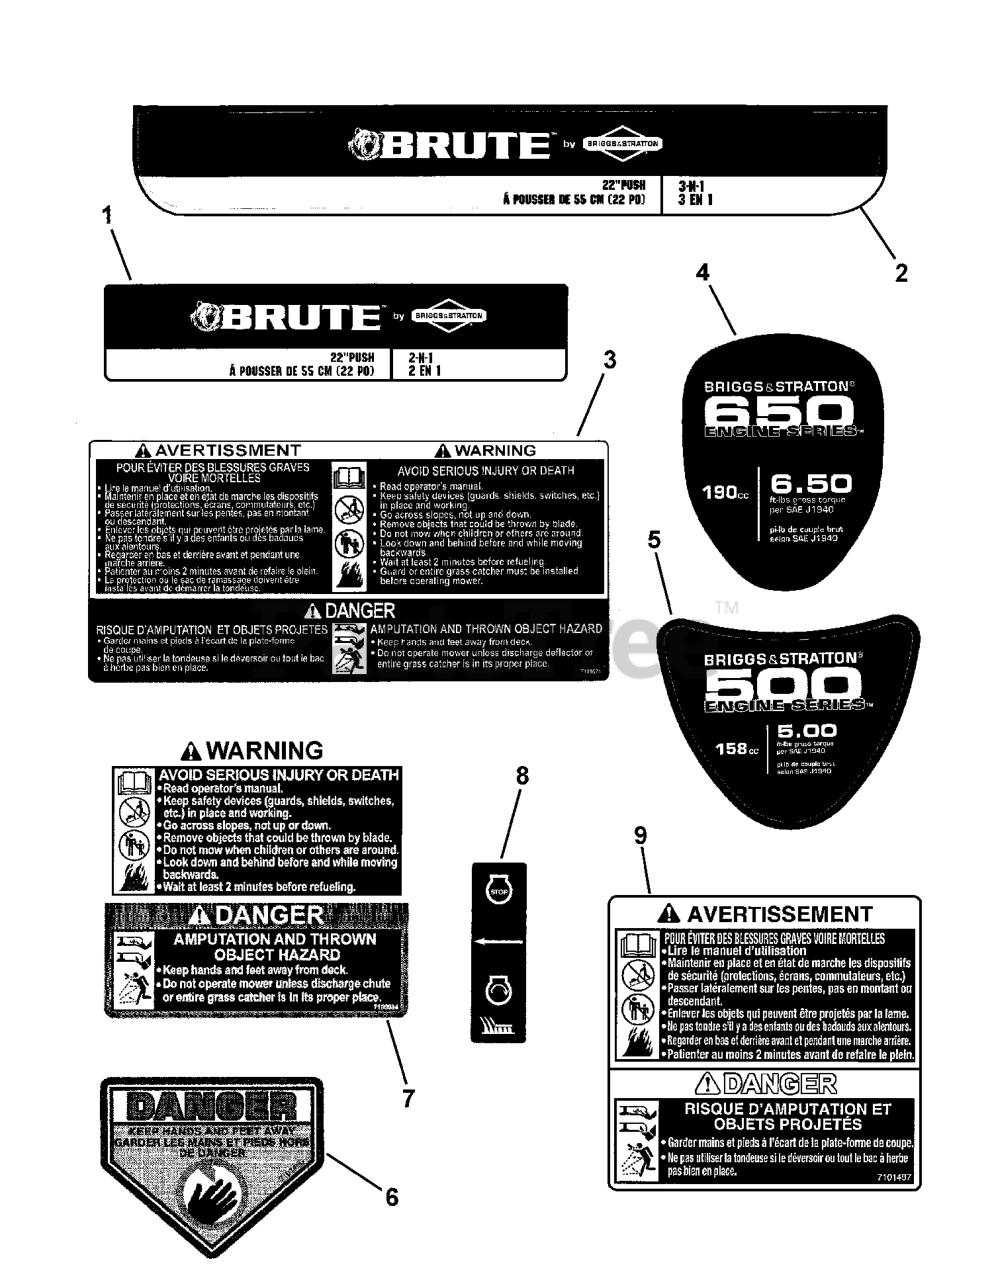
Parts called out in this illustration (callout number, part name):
1	DECAL, Brute Logo, Deck, FC
2	DECAL, Deck Front Brute 22" FC
3	DECAL, French/English, Walk-Behind Safety
4	DECAL, Engine, TP, Brute 650 FC
5	DECAL, Engine, Brute, TP, 500, FC
6	DECAL, CPSC, French/English
7	DECAL, Warning/Danger Walk-Behind Mower
8	DECAL, OPC Bail, International Symbol
9	DECAL, Warning/Danger, French/English
